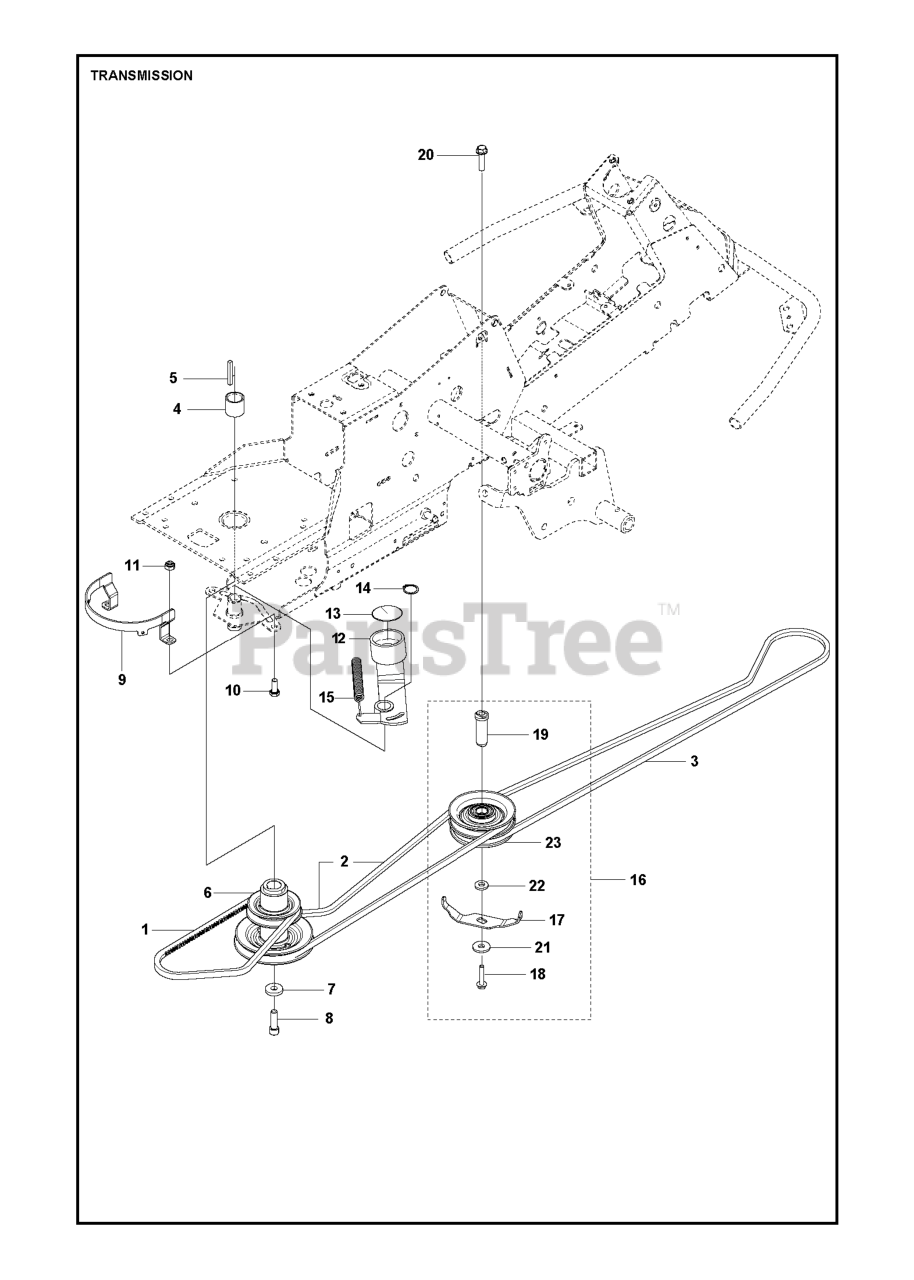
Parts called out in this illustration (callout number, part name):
1	BELT
2	BELT
10	Screw M10x25
14	RETAINING RING SGA 25
17	BELT GUIDE
